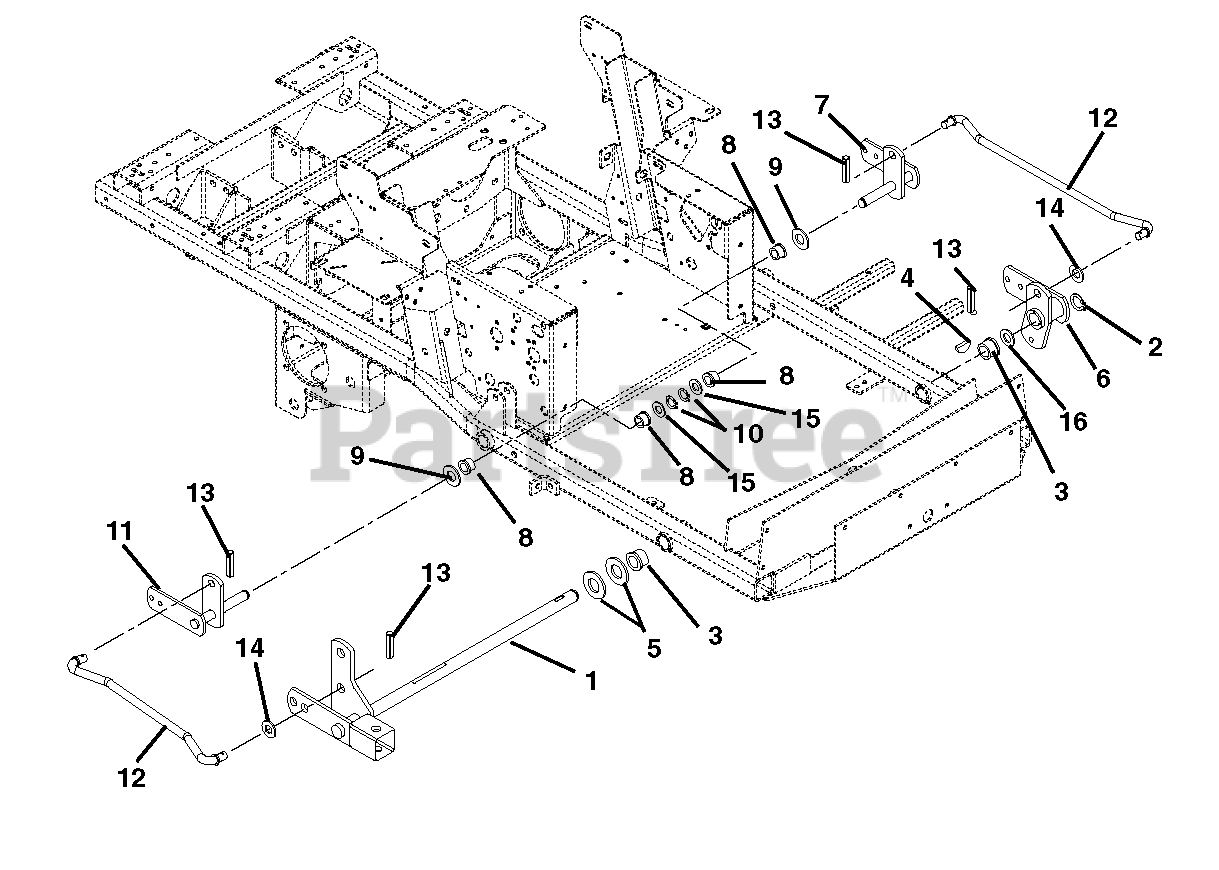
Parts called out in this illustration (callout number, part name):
1	Lift, Mower
2	Ring, Retaining External 1.00 x .078
3	Bushing 1.00 ID x 1.125 OD x 1.50
4	Key, Woodruff .25 x 1.00
5	Bushing 1.00 ID x 1.125 OD x 1.50
6	Weldment, Lift Arm - Front
7	Weldment, Rear Lift Arm – Left Hand
8	Bushing, Flange Nylon .762 x 1.0 x .58 x 1.48
9	Washer, Hardened Steel .758 x 1.23 x .031
10	Ring, Retaining External .689 x .077
11	Weldment, Rear Lift Arm – Right Hand
12	Rod, Lift Assist 19.35"
13	Pin, Roll .25 x 1.25 Stainless Steel
14	Washer, Flat Steel .630 x 1.25 x .062
15	Washer, Flat Steel .755 x 1.25 x .125
16	Washer, Hardened Thrust 1.00 x 1.55 x .03
